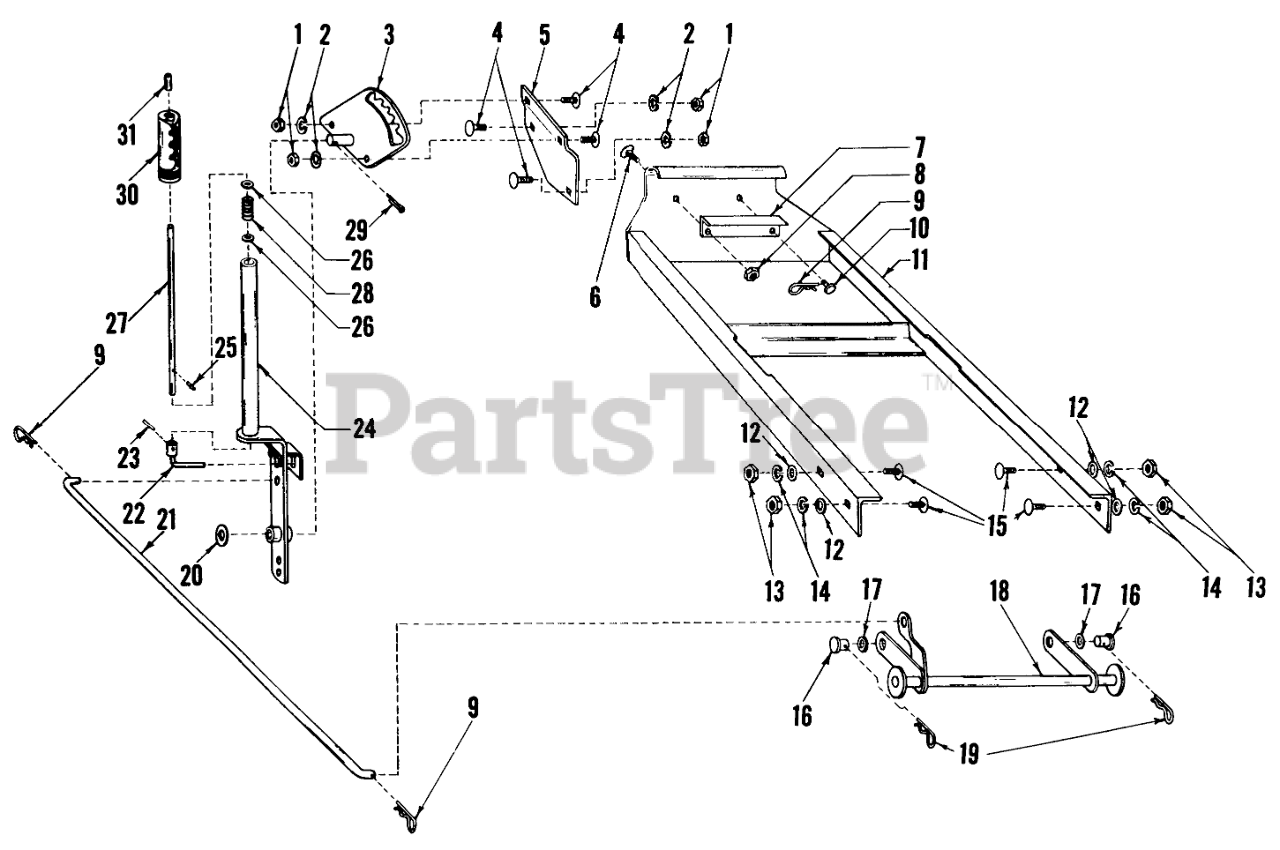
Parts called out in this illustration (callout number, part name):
3	Quadrant
4	Carriage Bolt
5	Lift Assembly Mounting Plate
6	Carriage Bolt
7	Latch
9	Hair Pin
11	Mounting Bracket
12	Washer
14	Washer
15	Carriage Bolt
16	Pin
17	Washer
18	Lift Assembly
19	PIN-COTTER
20	Washer
21	Lift Rod
22	Lift Lock
23	PIN-SPRING
24	Lower Handle
25	PIN-ROLL
26	WASHER-FLAT
27	Lift Rod
28	Spring
29	PIN-COTTER
30	Handle Grip
31	Cap
